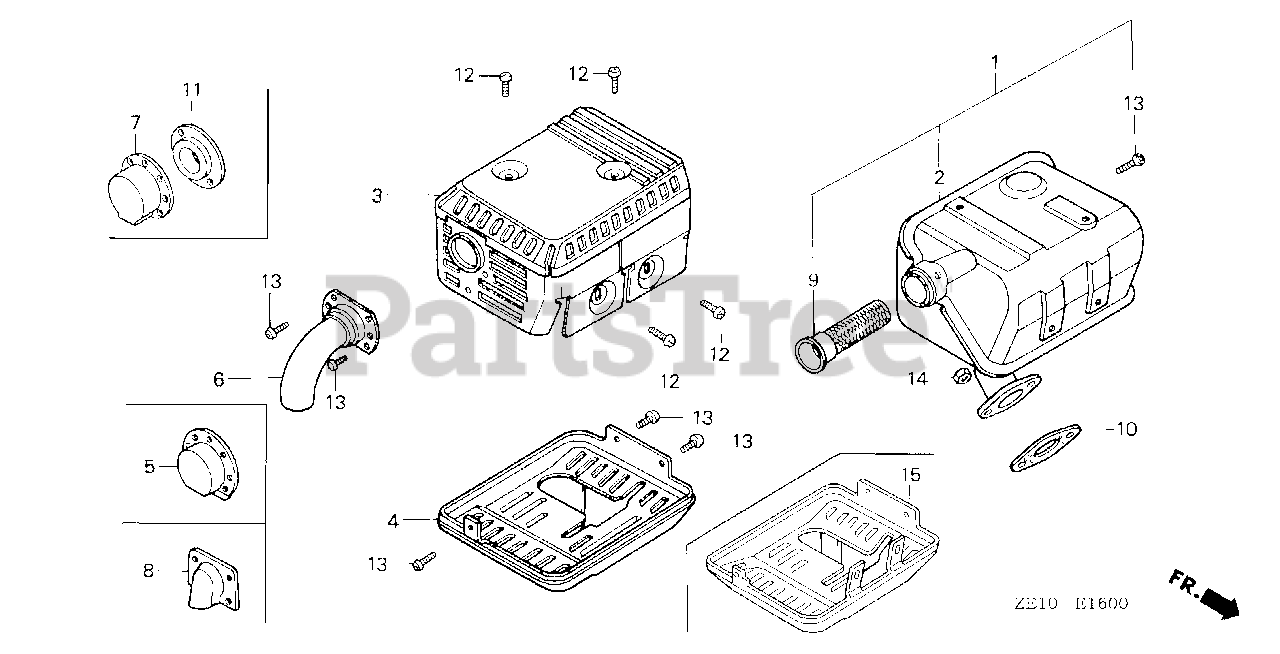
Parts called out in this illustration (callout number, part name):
1	MUFFLER (ARRESTER) Use up to Engine SN 1870782.
1	MUFFLER (ARRESTER)
2	MUFFLER (ARRESTER) Use up to Engine SN 1870782.
2	MUFFLER (ARRESTER)
3	PROTECTOR, MUFFLER (ALUMINIZED)
3	PROTECTOR (UPPER)
7	DEFLECTOR
9	ARRESTER, SPARK
10	GASKET, MUFFLER
11	GUIDE, MUFFLER
12	SCREW, TAPPING (5X8)
13	SCREW, TAPPING (4X6)
14	NUT, HEX. (8MM)
